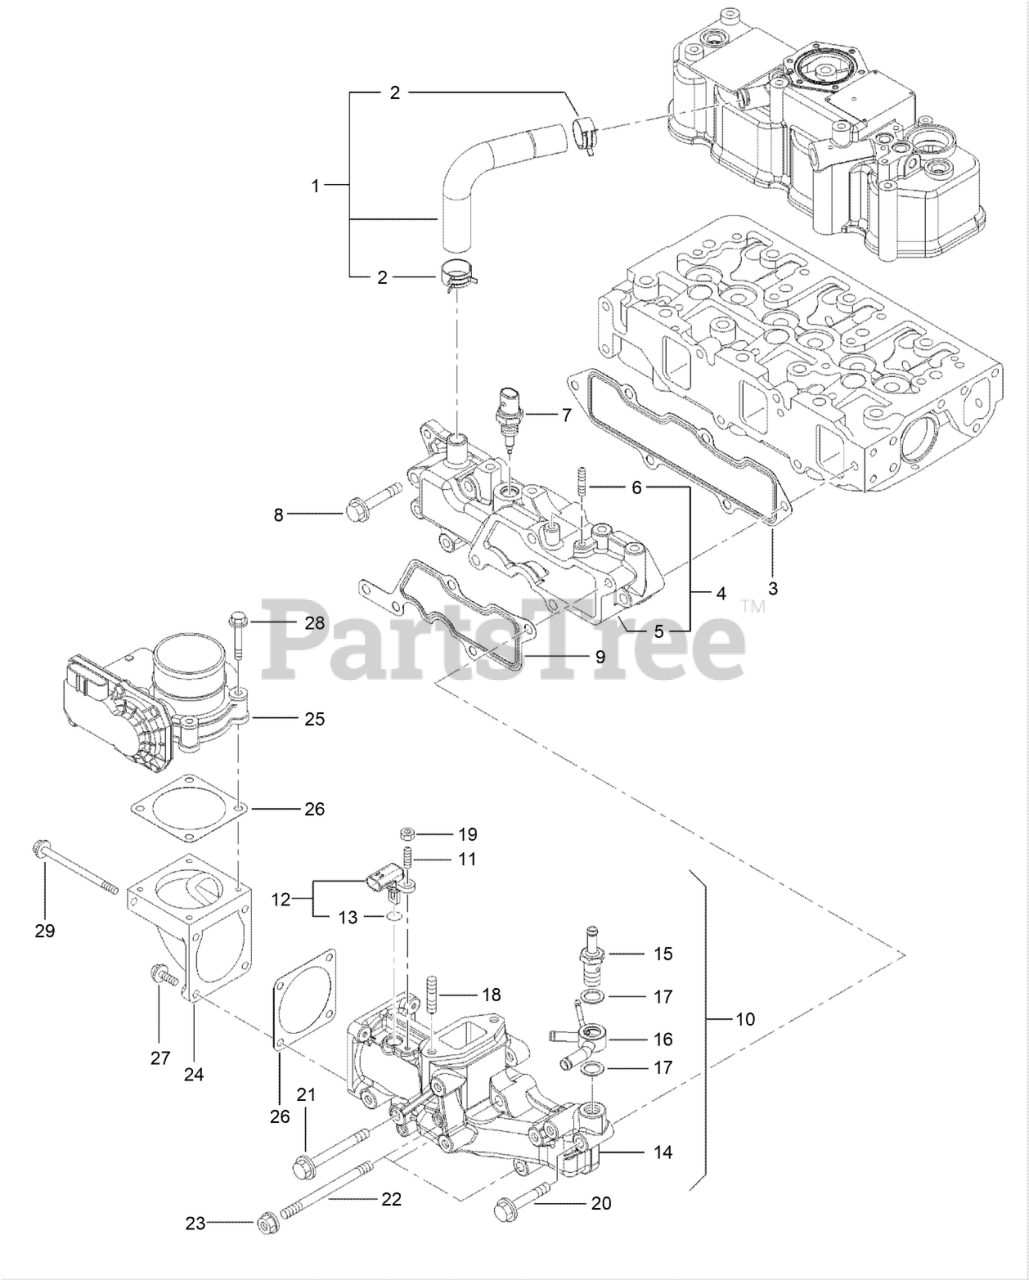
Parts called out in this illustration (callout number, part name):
2	CLIP-HOSE
3	GASKET-MANIFOLD, INTAKE
4	INTAKE MANIFOLD ASM
5	MANIFOLD-INTAKE
7	SENSOR-TEMPERATURE, AIR
9	GASKET-COLLECTOR
10	INTAKE COLLECTOR ASM
12	SENSOR-TEMP, AIR
13	O-RING
14	COLLECTOR-INTAKE
15	JOINT-HOSE
16	JOINT-HOSE
17	WASHER-SEAL
24	BEND-INLET
25	BODY-THROTTLE
26	GASKET-THROTTLE
